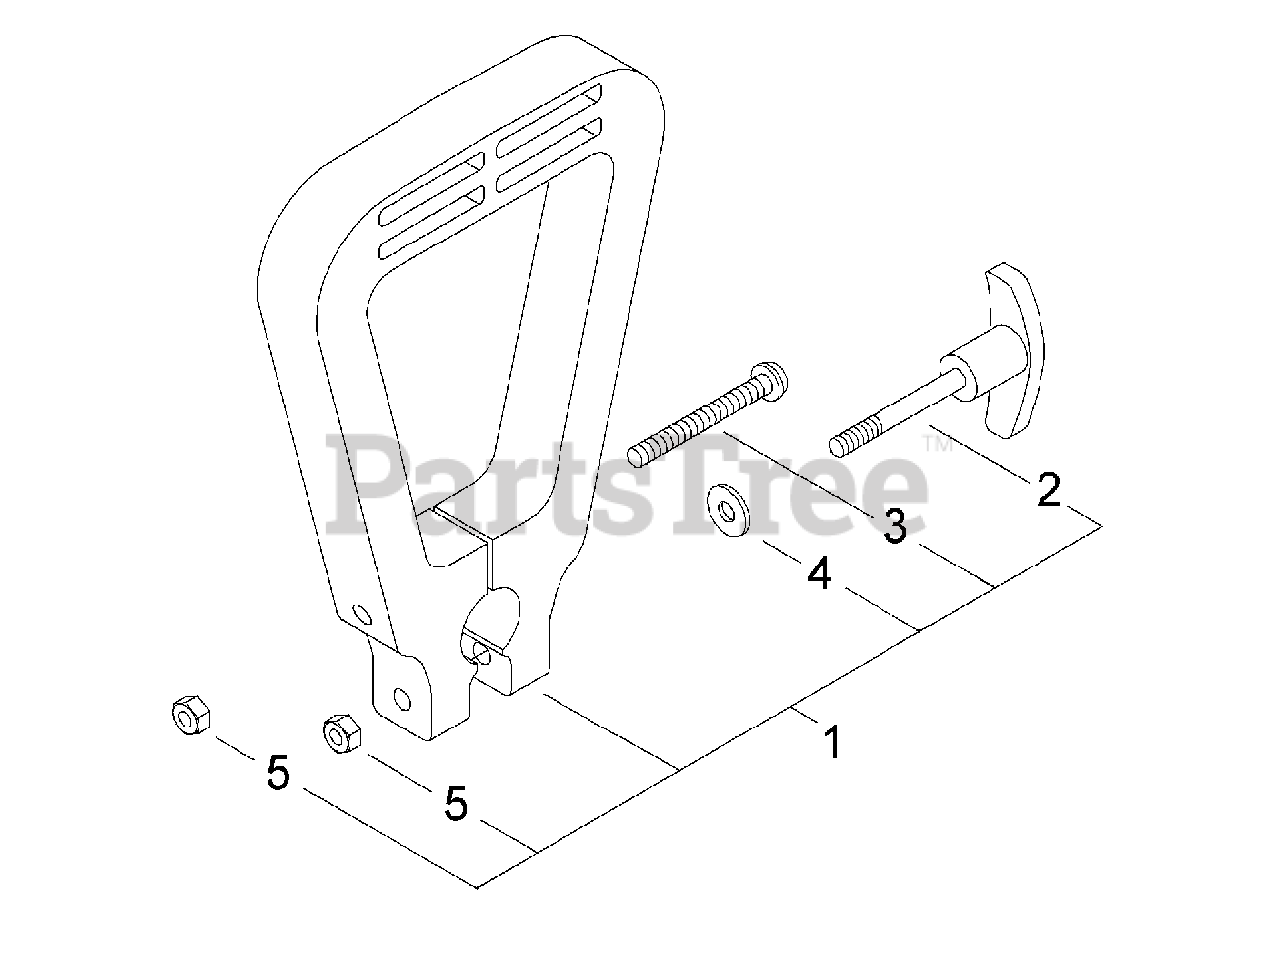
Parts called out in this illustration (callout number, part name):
1	HANDLE ASSY
2	KNOB, SCREW
3	SCREW 6
4	WASHER 6
5	NUT, HEX M6
